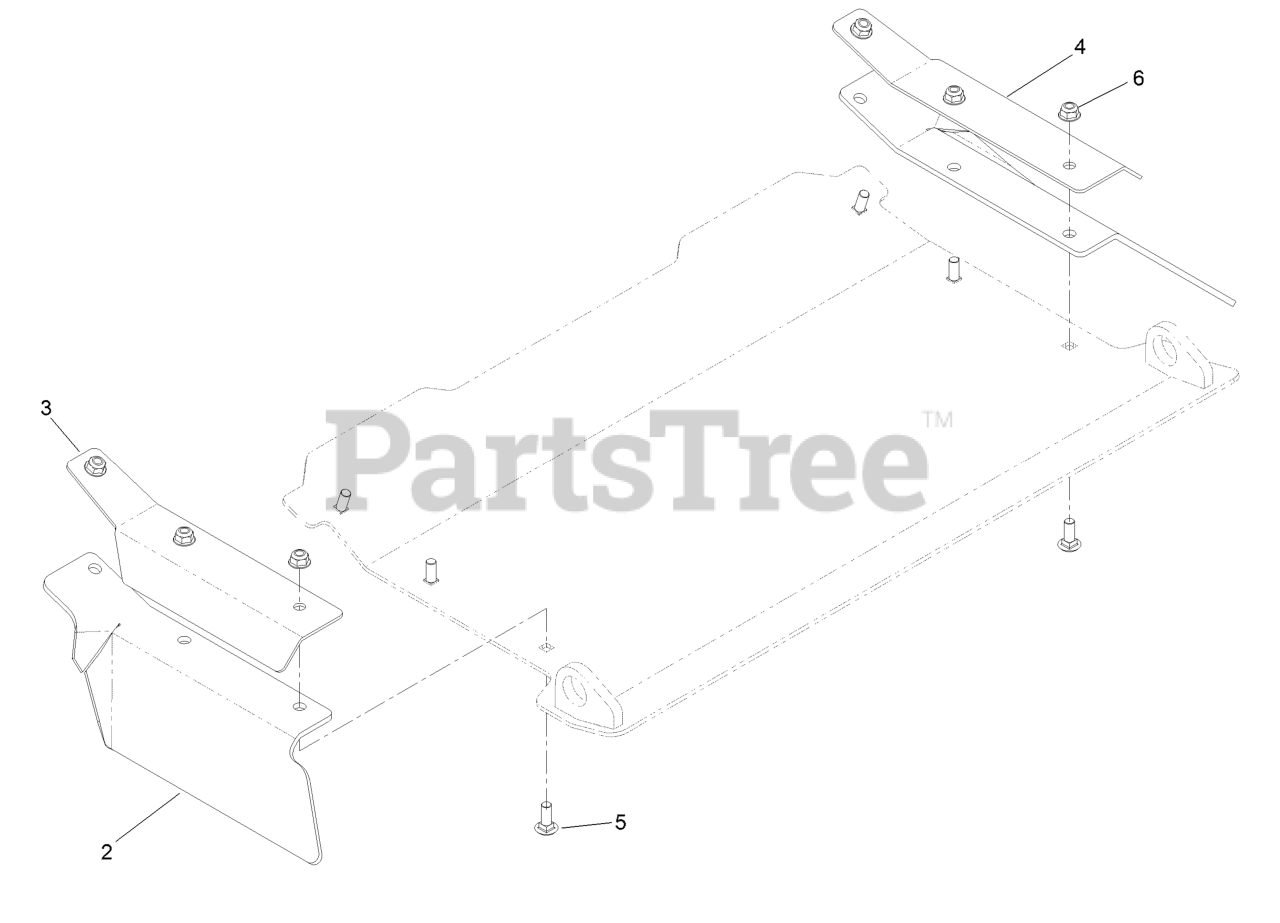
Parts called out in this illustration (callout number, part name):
2	Flap-Rubber
3	Bracket-Flap, LH
4	Bracket-Flap, RH
5	Screw-CARR
6	Nut-HF, NI
